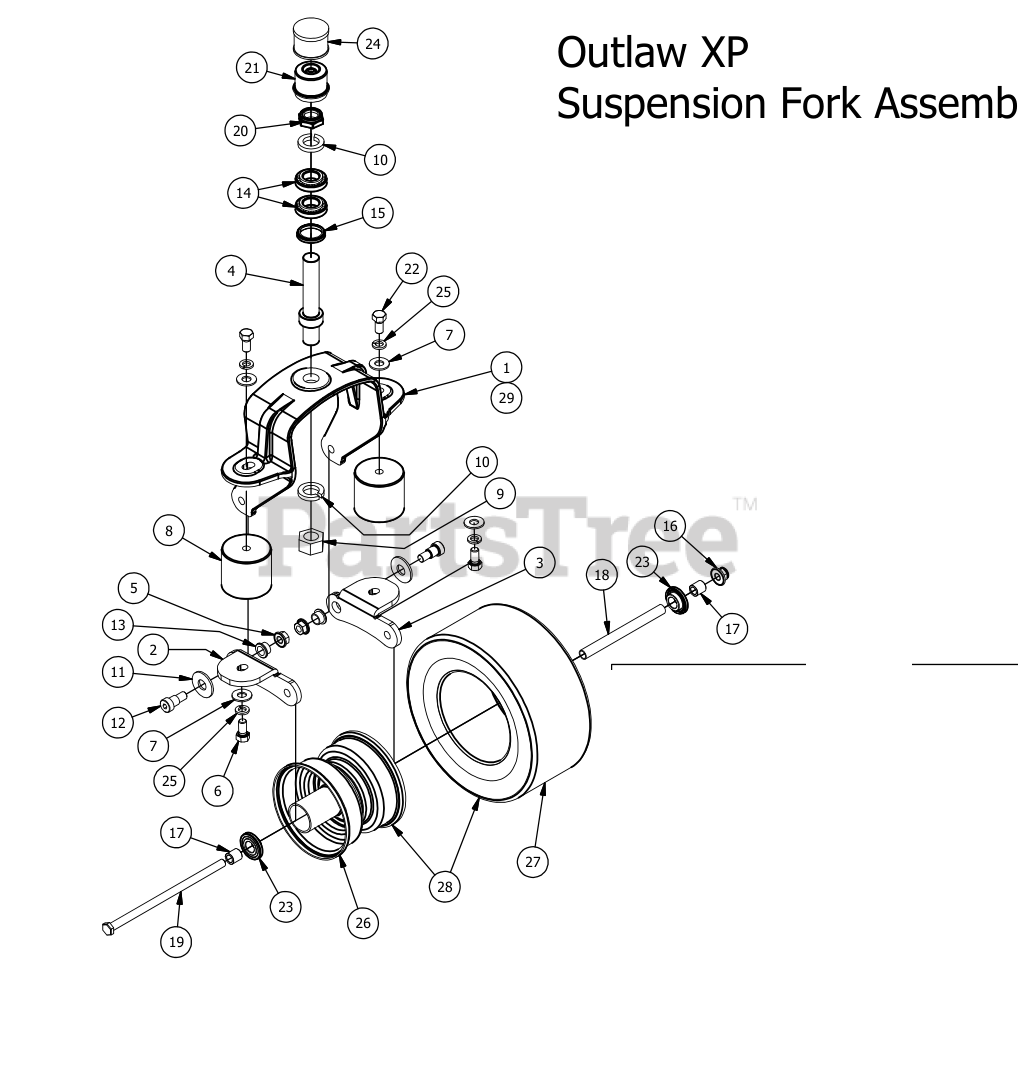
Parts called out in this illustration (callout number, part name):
1	Suspension Fork Top/Side Combo
2	Suspension Fork - Bottom Left
3	Suspension Fork - Bottom Right
4	Front Suspension Fork Spindle
5	1/2" Flange Nut
6	1/2" x 1" Hex Bolt
7	1/2" Washer (Grade 8)
8	Vibration Mount- Red Dot
9	1" Fine Thread Nut
10	1" Lock Washer
11	5/8" Flat Washer
12	5/8" x 5/8" Shoulder Bolt
13	Bronze Bushing - SF - 2024-8
16	1/2-13 Nylon Flange Nut
17	Spacer 3/4 OD x 1/2 ID x 3\4 Length
18	Front Wheel Spanner
19	1/2" x 10" Bolt
20	1" Fine Thread 1/2 Nylock Nut
21	Dust Cover
22	1/2" x 1-1/4" Gr5 Hex Bolt (Coarse)
23	1-3/4" Bearing-Large Bore Front Rim
24	Spring Cap Cover
25	1/2" Lock Washer
26	Black Front Tire Rim
27	13 x 6.50 6 Tire
28	13x6.5-6 Large Bore - Black Front Assembly
29	Suspension Fork Assembly
